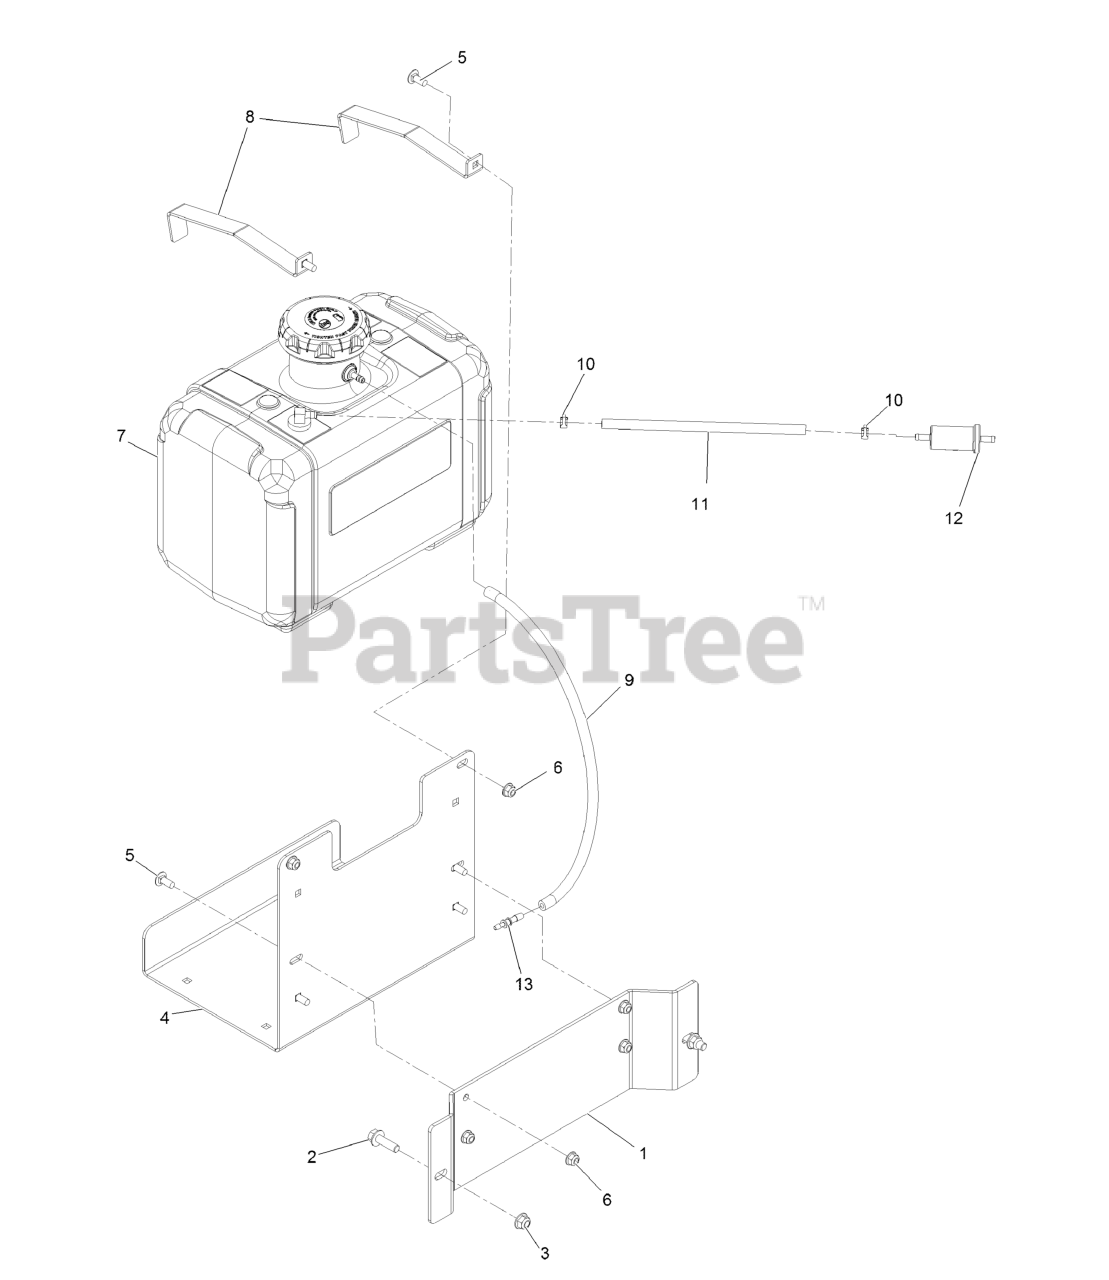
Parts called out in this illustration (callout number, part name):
1	MOUNT, GAS TANK, AE
2	SCREW-HHF
3	NUT-HF, NI
4	Mount-Tank,Bracket
5	SCREW-CARR
6	NUT-HF, NI
7	ASM-Tank, 5 Gal.
8	Strap-Tank, Ae
9	HOSE-FUEL
10	CLAMP-HOSE
11	HOSE-FUEL
12	FILTER-FUEL
13	BARB-FUEL
